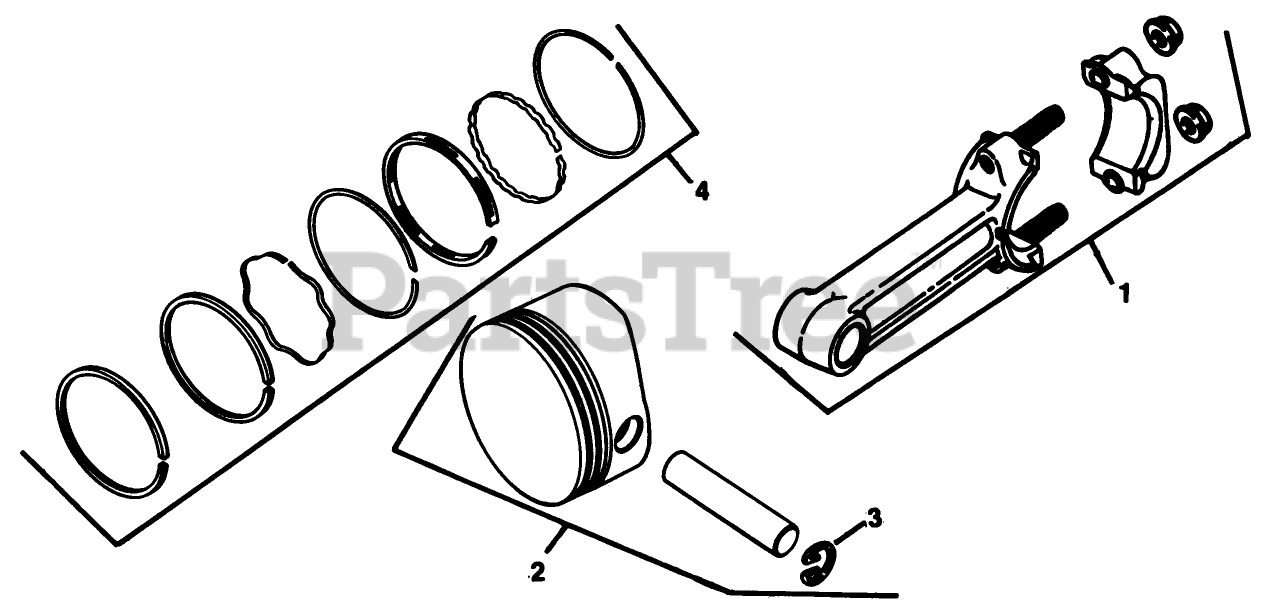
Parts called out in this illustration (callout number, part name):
1	Connecting Rod Assy. (Std.)
1	Connecting Rod Assembly (.010 U.S.)
2	Piston Assembly (Std)
3	Retainer-Piston Pin
4	Ring Set (Std & .003)
